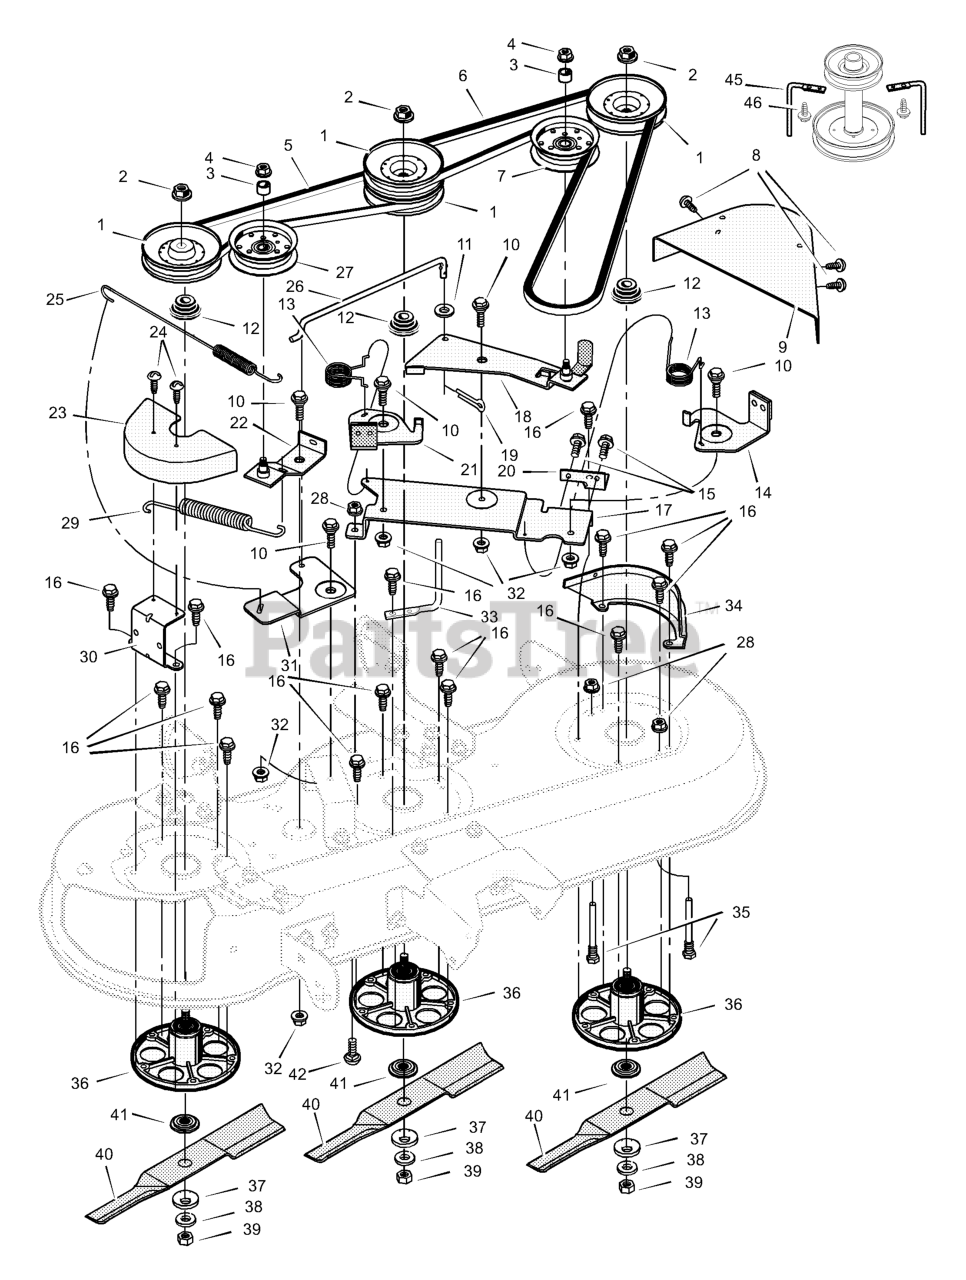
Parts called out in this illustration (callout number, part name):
1	Pulley
4	Nut, Centerlock
5	Belt, Secondary
6	Belt, Primary
7	V-Pulley
9	Cover, Left Pulley
10	Bolt, Shoulder
11	Washer
12	Spacer, Pulley
13	Spring, Torsion
14	Assembly, Left Brake
16	Screw
17	Plate, Brake Arm
18	Assembly, Idler Arm
19	Pin, Cotter
20	Bracket, Brake Plate Mount
21	Assembly, Center Brake
22	Assembly, Right Idler Arm
23	Cover, Right Pulley
24	Screw
25	Spring, Extension
26	Link, Bell Crank
27	Pulley, Backside
28	Nut, Flange
29	Spring, Extension
30	Cover, Bracket
31	Crank, Bell
32	Nut
33	Guide, Belt
34	Bracket, Pulley Cover
35	Guide, Belt
36	Assembly, Jackshaft Housing
37	Washer, Belleville
38	Washer
39	Nut
41	Adapter, Blade
42	Bolt, Carriage
45	Guide, Belt
46	Screw
